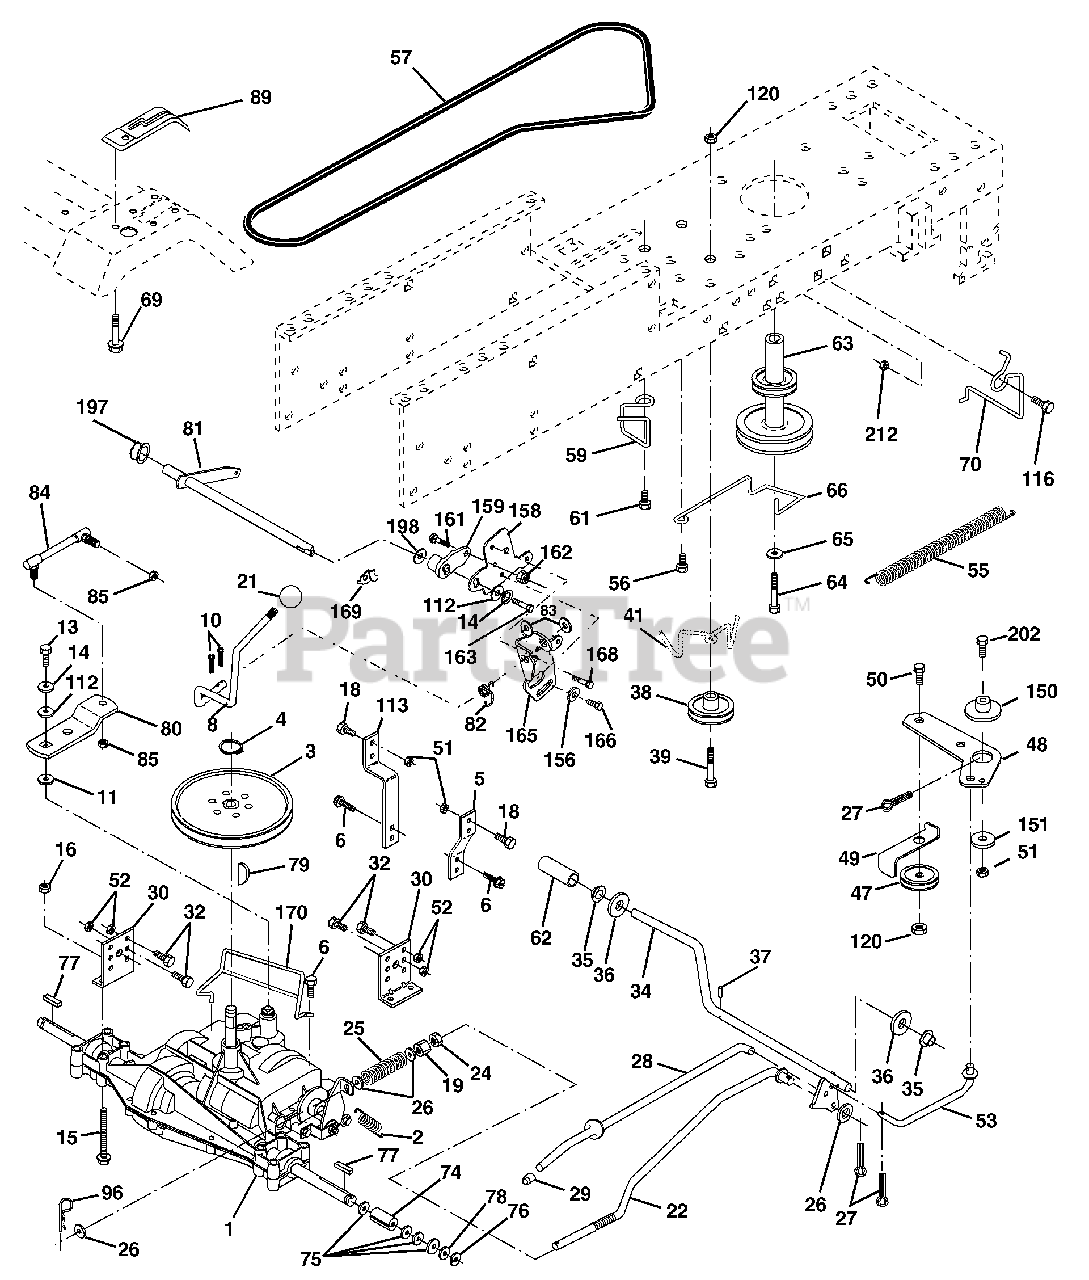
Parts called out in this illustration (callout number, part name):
2	Spring Return Brake T/a Zinc
3	Pulley Transaxle 18" tires
4	Ring Retainer # 5100-62
5	Strap Torque 30 Degrees
6	Screw 5/16-18 X 3/4
8	Rod Shift Fender Adjust Lt
10	Pin Cotter 1/8 X 1 Cad
11	Washer Plate Shf 388 Sq Hole
13	Bolt 1/4-28 Unf Gr. 8 W/Patch
14	Washer Lock Hvy Helical
15	Bolt Hex FLGHD 5/16-18 Gr. 5
16	Nut Lock Hex w/ins 5/16-18
18	Bolt, Fin Hex 3/8-16 unc x 1 Gr. 5
19	Nut Lock 3/8-16 Unc
21	Knob
22	Rod Brake Blk Zinc 26 840
24	Nut Hex Jam 3/8-16 unc
25	Spring Rod Brake 2 00 Zinc
26	Washer 13/32 x 13/16 x 16 Ga.
27	Pin Cotter 1/8 x 3/4 Cad
28	Rod Brake Parking LT/YT
29	Cap Brake Parking
30	Bracket Mtg Transaxle
32	Bolt Hex Hd 5/16-18 unc x 3/4
34	Shaft Asm Pedal Foot
35	Bearing Nylon Blk 629 Id
36	Washer 21/32 x 1 x 16 Ga.
37	Pin Roll 3/16 X 1"
38	Pulley Composite Flat
39	Bolt RDHD 3/8-16 unc x 2-3/4 Gr. 5
41	Keeper Belt Flat Idler
47	Pulley Idler V Groove Plastic
48	Bellcrank Asm
49	Retainer Belt Style Spring
50	Bolt Carr. Sh. 3/8-16 x 1-1/2 Gr. 5
51	Nut Crownlock 3/8-16 unc
52	Nut Crownlock 5/16-18 unc
53	Link Clutch
55	Spring Return Clutch 6 75
56	Screw 3/8-16 x 1-1/4
57	V-Belt Ground Drive 95 25
59	Keeper Belt Span Ctr
61	Screw 3/8-16 x .875
62	Cover Pedal Blk Round
63	Engine Pulley
64	Bolt Hex
65	Washer Lock Hvy Hlcl Spr 7/16
66	Keeper Belt Engine Foolproof
69	Screw Hex wsh Hi Lo 1/4 x 1/2 unc
70	Guide Belt Mower Drive RH
74	Spacer Axle
75	Washer 25/32 x 1 1/4 x 16 Ga.
76	E-ring #5133-75
77	Key Square 2 0 x 1845/ 1865
78	Washer 25/32 x 1-5/8 x 16 Ga.
79	Key Woodruff #9 3/16 x 3/4
80	Arm Shift
81	Shaft Asm Cross Tapered PMST/20
82	Spring Torsion T/a
83	Washer 17/32 x 3/4 x 16 Ga.
84	Link Transaxle PMST/18" Zinc
85	Nut Lock Center 1/4 - 28 FNTHD
89	Console Shift STLT
96	Retainer Spring 1"
112	Washer 9/32 x 3/4 x 10 Ga.
113	Strap Torque LT
116	Bolt Rdhd Sq Neck 3/8-16 x 1
120	Nut Lock Flg. 3/8-16 unc
150	Spacer Retainer
151	Washer 13/32 x 2 x 10
156	Washer Srrted 5/16ID x 1.125
158	Bracket Shift Mount
159	Hub Tapered Flange Shift Lt
161	Bolt Rdhd Sqnk 1/4-20 x 3/4
162	Nut Crownlock 1/4-20 unc
163	Bolt Hex Fin 1/4-20 unc x 1 Gr. 5
165	Bracket Pivot Lever
166	Screw 5/16-18 x 5/8
168	Bolt Shoulder 5/16-18 x .561
169	Plate Fastening
170	Keeper Belt Transaxle Gear
197	Nyliner Snap-In
198	Washer Nyliner
202	Bolt Rd Hd 3/8-16 unc x 1-3/4 Gr. 5
212	Nut Hexflange Lock
